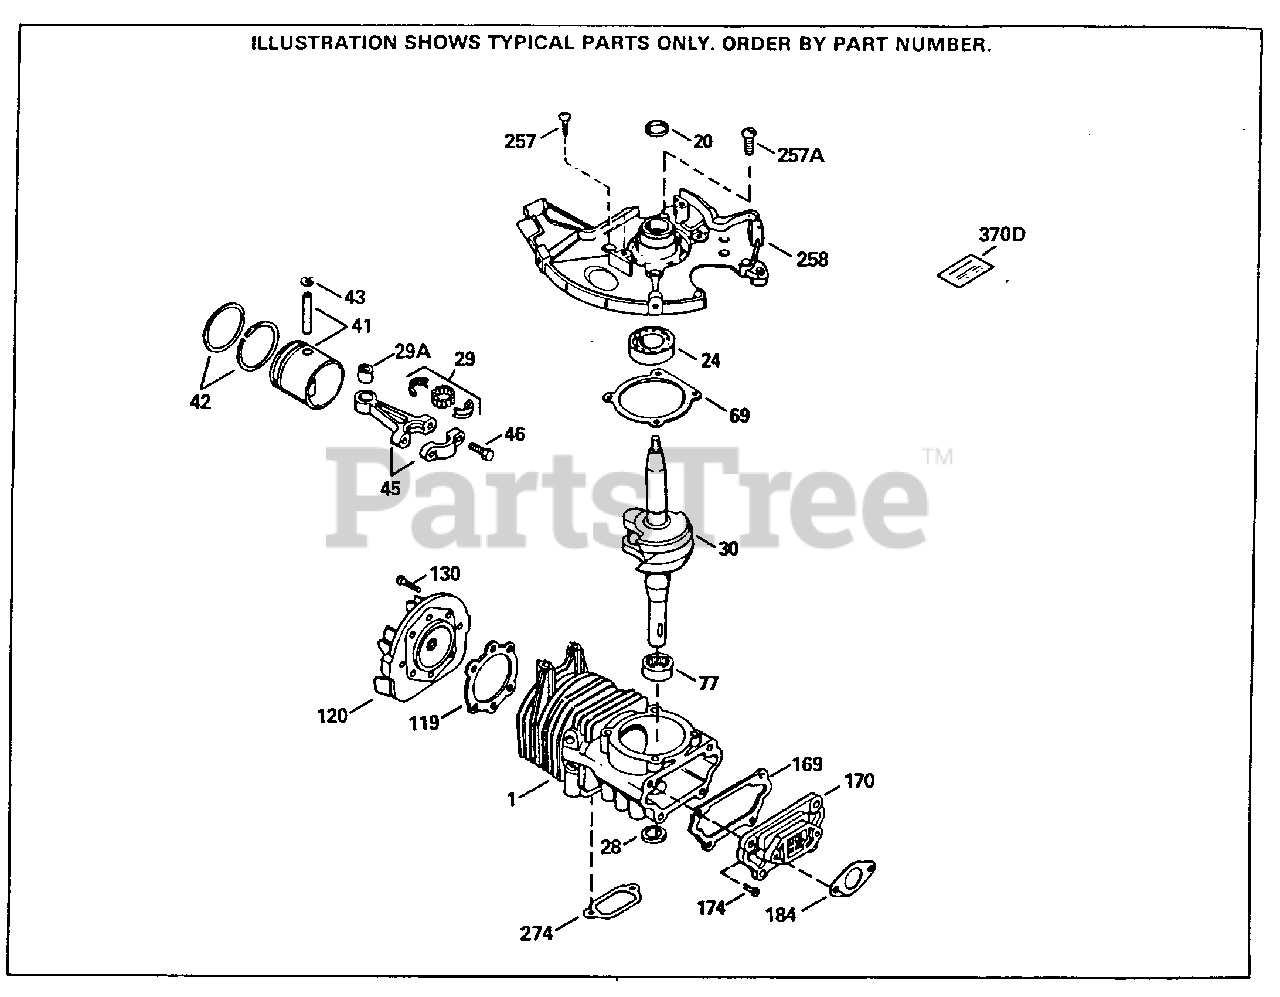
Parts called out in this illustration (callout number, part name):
1	"Cylinder Order SB if replacement isre q.
20	Seal, Crankshaft
24	Bearing, Ball
28	Oil Seal
29	Bearing & Liner Set, Needle
29A	Bearing, Cartridge
30	Crankshaft
41	Piston & Pin Assy. (Incl. 43)
42	Ring Set, Piston
43	Ring, Piston pin retaining
45	Rod Assy., Connecting Incl. 29, 29A& 46
46	Screw, Connecting rod
69	Gasket, Housing base
77	Bearing, Cartridge
119	Gasket, Cylinder head
120	Cylinder Head
130	Screw, Torx T-30, 1/4-20 x 3/4"
169	Gasket, Reed plate
170	Plate Assy., Reed
174	Screw, Torx T-25, 10-24 x 1/2"
184	Gasket, Carburetor
257	Screw, Torx T-30, 1/4-20 x 5/8"
257A	Screw, Torx T-30, 1/4-20 x 1/2"
258	Housing Base (Incl. 20)
274	Gasket, Exhaust
370D	Decal, Warning
